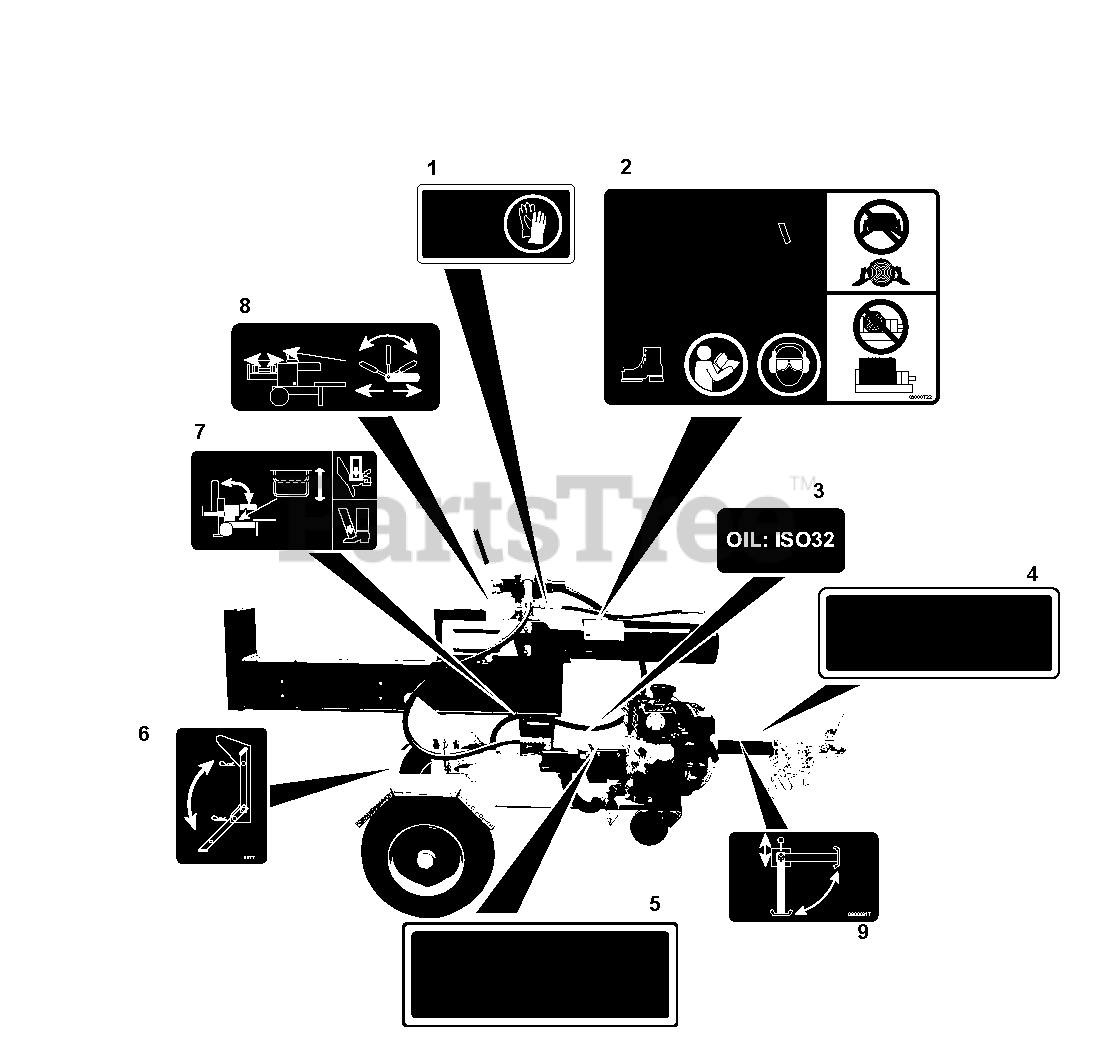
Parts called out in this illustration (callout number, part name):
1	Decal, Hydraulic Warning
2	Decal, Danger Log Splitter
3	Decal, Log Splitter Hydraulic Oil
4	Decal, Towing
5	Decal, Fuel Warning
6	Decal, Log Splitter Rear Stand
7	Decal, Log Splitter Tilt Operation
8	Decal, Log Splitter Ram Operation
9	Decal, Log Splitter Front Stand
